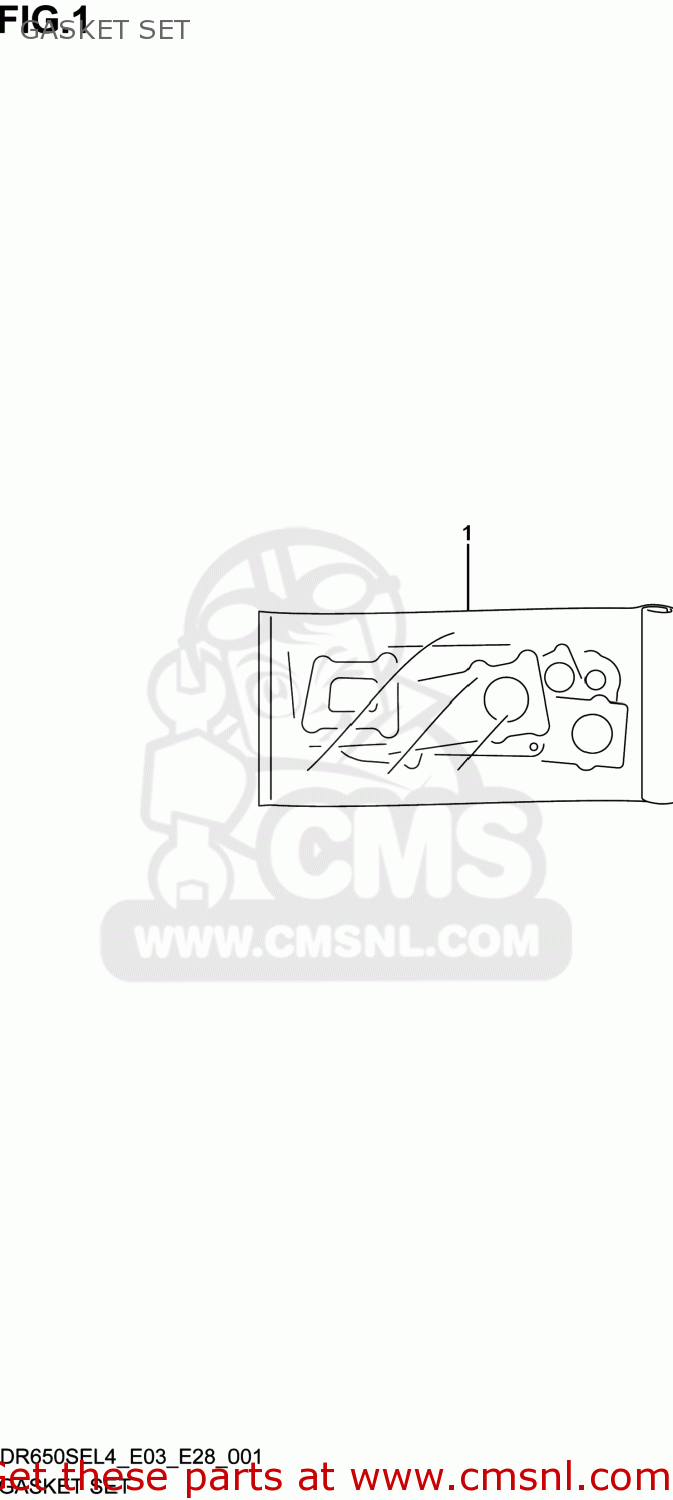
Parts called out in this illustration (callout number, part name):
1	GASKET SET (NAS)
2	GASKET,CYLINDER HEAD
3	O RING,INSPECTION CAP
4	GASKET,CYLINDER (NAS)
5	GASKET,CLUTCH COVER
6	GASKET,MAGNETO COVER
7	GASKET,GEAR SHIFT COVER (NAS)
8	GASKET,TENSIONER ADJUSTER (NAS)
9	GASKET,EXHAUST PIPE (NAS)
10	O RING(D:2.4,ID:15.8)
11	O RING(D:3.1,ID:16.8)
12	O RING(D:2.4,ID:45.7)
13	O RING(D:2.4,ID:73)
